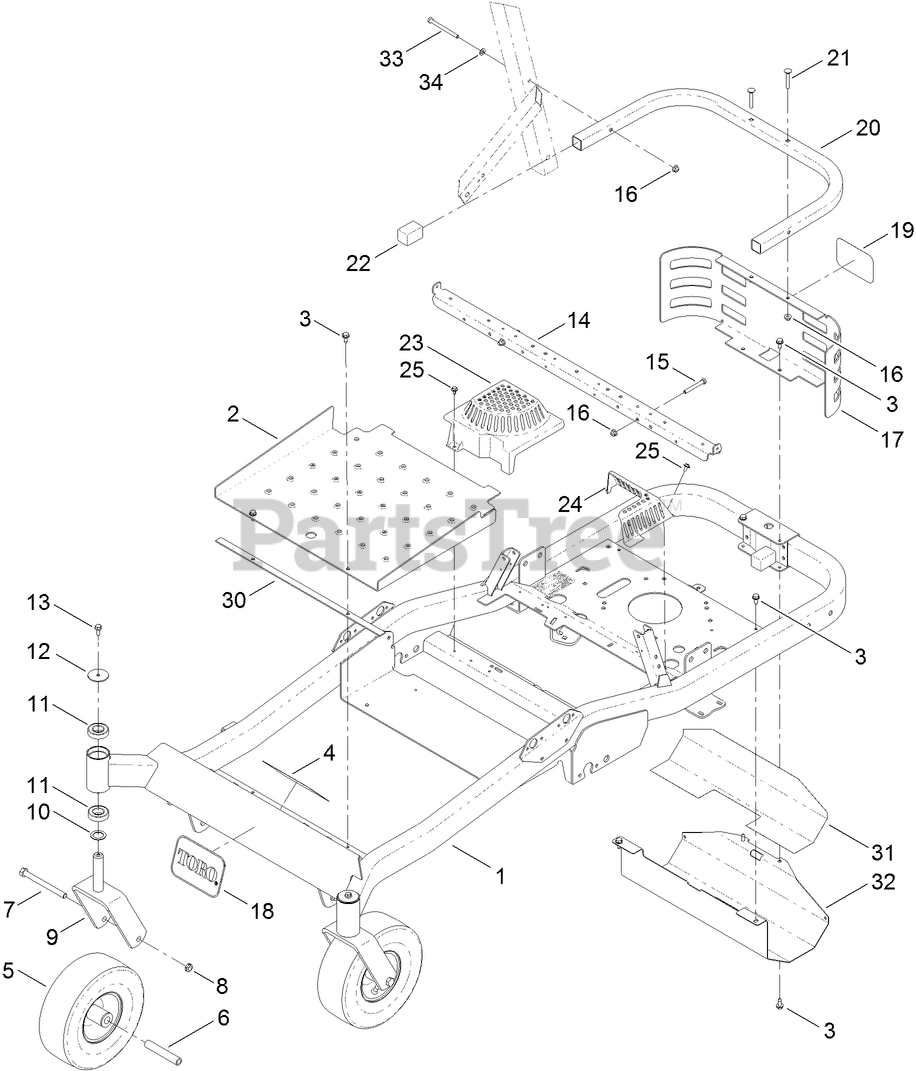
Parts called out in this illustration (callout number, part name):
2	PAN-FLOOR
3	SCREW-HWHTF
4	DECAL-SAFETY
5	TIRE AND WHEEL ASM (KENDA)
6	BUSHING-SPANNER
7	SCREW-HH
8	NUT-HEX
9	CASTER FORK ASM
10	WASHER-THRUST
11	BEARING-BALL
12	WASHER
13	SCREW-HHF
14	SUPPORT-SEAT
15	SCREW-HH
16	NUT-HF, NI
17	GUARD-REAR
18	DECAL
20	TUBE-GUARD
21	BOLT-CARR
23	COVER-FAN, RH
24	COVER-FAN, LH
25	SCREW-HHFTF
30	STRIP-VIBRATION, ANTI
31	FOIL-HEAT SHIELD
33	SCREW-HH
34	WASHER-PLAIN
